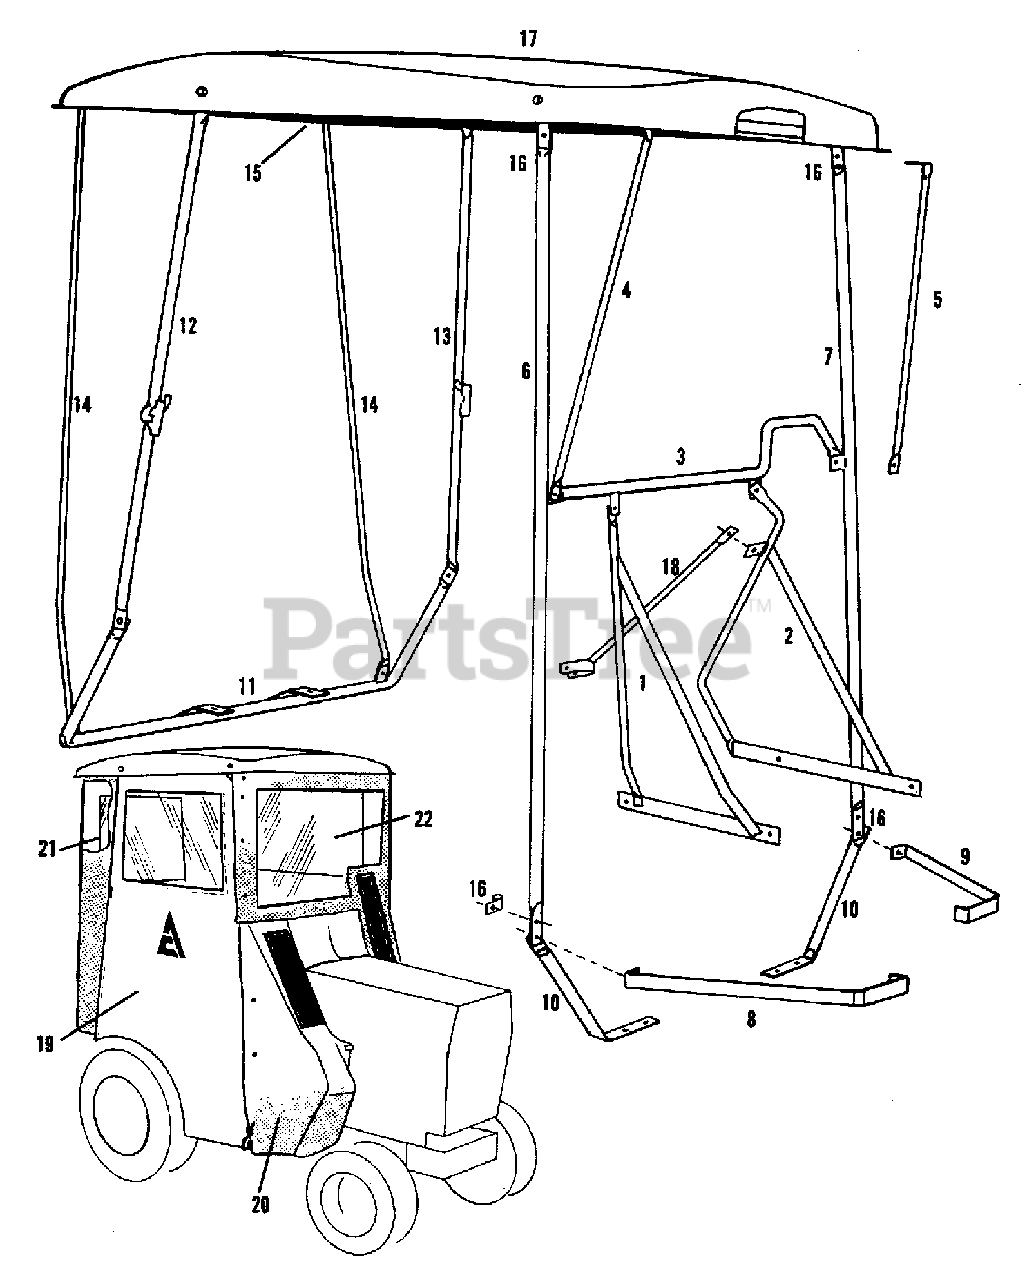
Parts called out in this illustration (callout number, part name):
1	BRACKET, Front Attaching, R.H.
2	BRACKET, Front Attaching, L.H.
3	BAR, Front Cross
3	CAPSCREW, 1/4NC x 3/4
3	NUT, 1/4NC, Lock
4	BRACE, Top, R.H.
5	BRACE, Top, L.H.
5	CAPSCREW, 1/4NC x 1-1/4
5	NUT, 1/4NC, Lock
6	POST, Front Corner, R.H.
7	POST, Front Corner, L.H.
8	BRACE, Foot Pocket, R.H.
9	BRACE, Foot Pocket, L.H.
9	CAPSCREW, 1/4NC x 3/4
9	NUT, 1/4NC, Lock
10	FOOT, R.H. & L.H.
10	CAPSCREW, 1/4NC x 3/4
10	NUT, 1/4NC, Lock
11	BRACKET, Rear Attaching
12	POST, Rear Corner, R.H.
13	POST, Rear Corner, L.H.
13	CAPSCREW, 1/4NC x 3/4
13	NUT, 1/4NC, Lock
14	POST, Rear Curtain R.H. & L.H.
14	CAPSCREW, 1/4NC x 3/4
14	NUT, 1/4NC, Lock
15	CAPSCREW, 1/4NC x 3/4
15	NUT, 1/4NC, Lock
16	HINGE, Door
16	CAPSCREW, 1/4NC x 3/4
16	NUT, 1/4NC, Lock
17	TOP, Fiber Glass
17	CAPSCREW, 1/4NC x 3/4
17	WASHER, 1/4, Lock
17	NUT, 1/4NC, Lock
18	BRACKET, Auxiliary Front, Attaching L.H.
18	CAPSCREW, 1/4NC x 2-1/4
18	CASPSCREW, 1/4NC x 3/4
18	NUT, 1/4NC, Lock
19	DOOR, R.H.
19	DOOR, L.H.
20	PANEL, Front Vinyl
21	CURTAIN, Rear Vinyl
22	WINDSHEILD, Plastic
